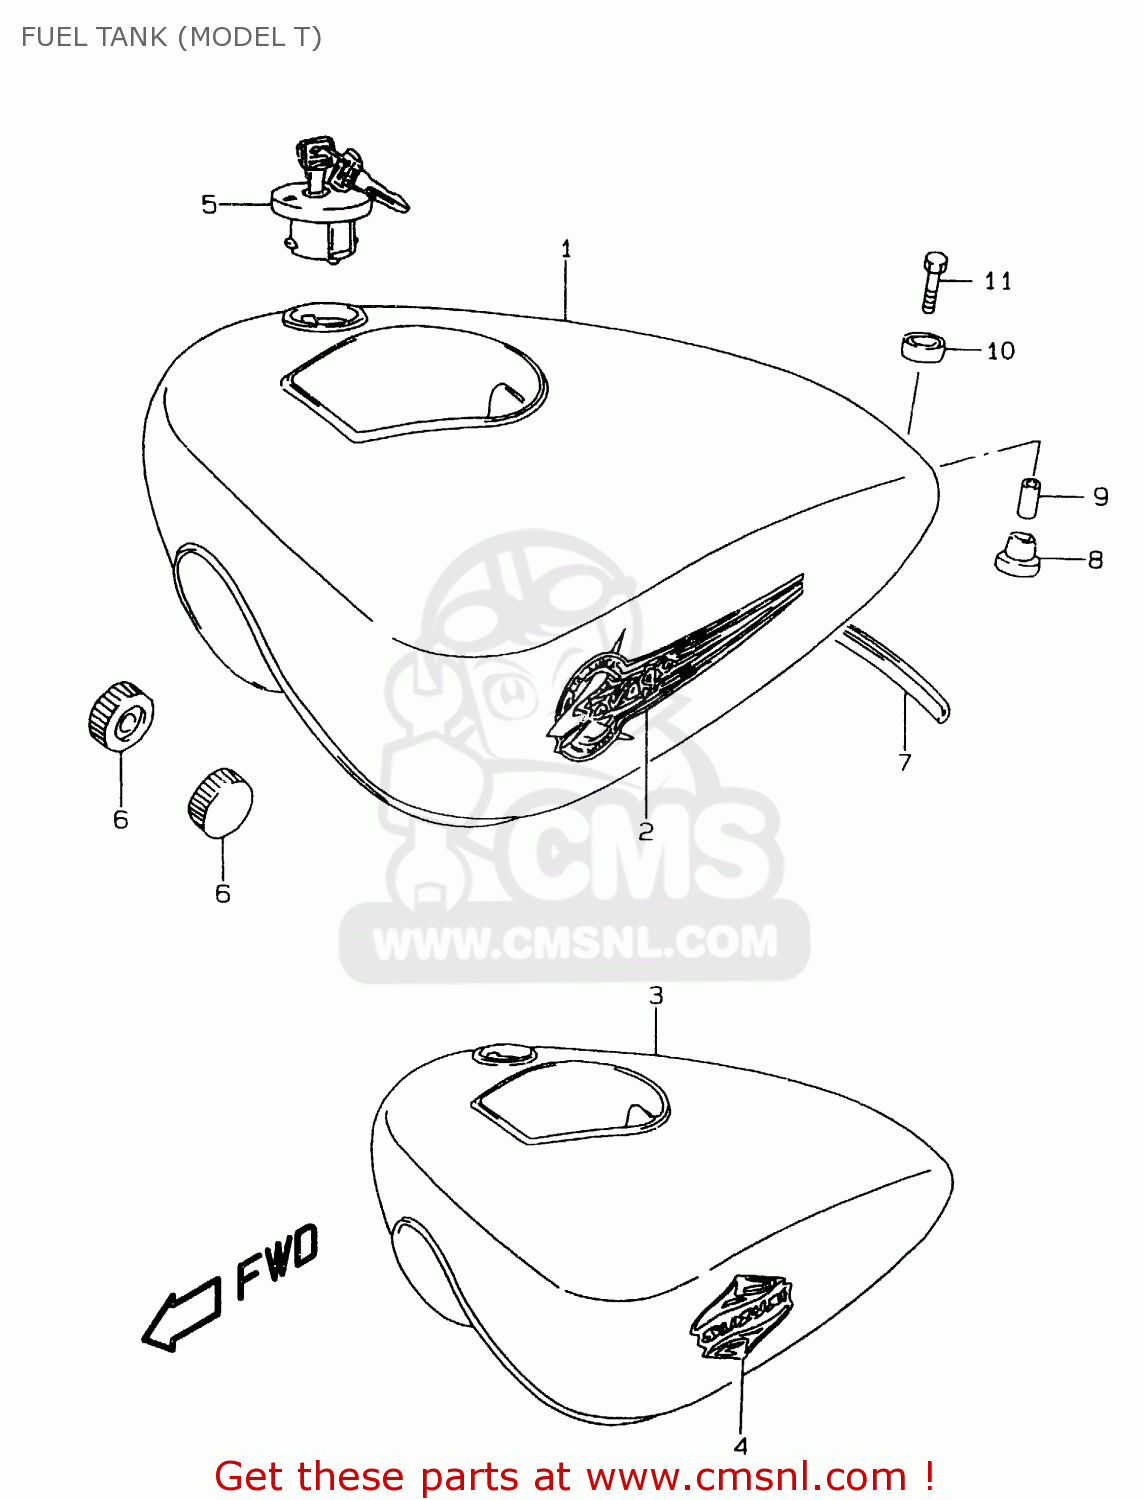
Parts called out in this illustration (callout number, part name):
1	TANK ASSY,FUEL
2	TAPE SET,FUEL TANK
3	TANK ASSY, FUEL (BLACK)
4	EMBLEM
5	CAP SET,FUEL TANK
6	CUSHION
7	MOLDING,FUEL TANK RR
8	CUSHION
9	SPACER
10	CUSHION
11	BOLT
